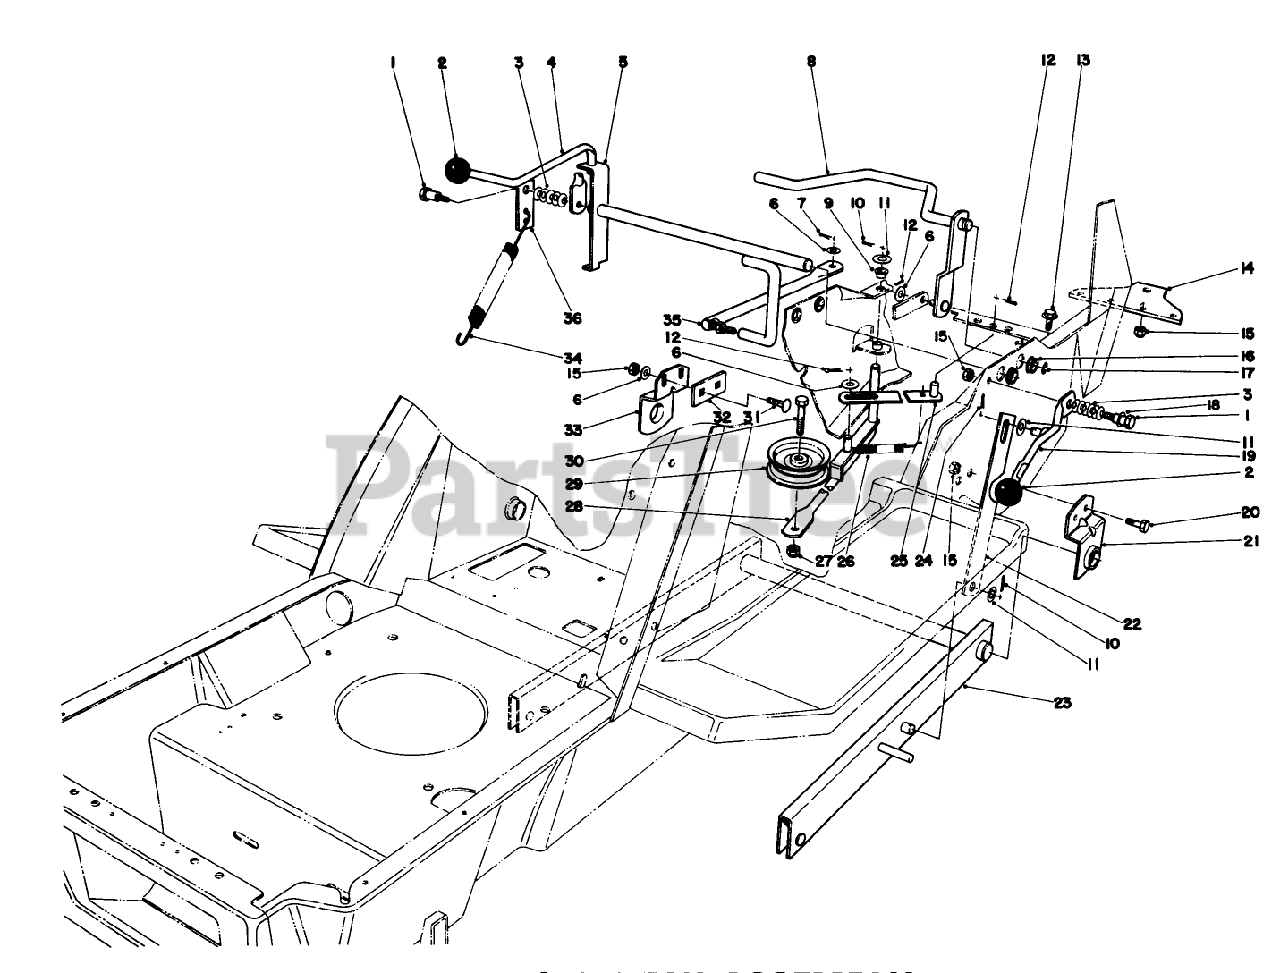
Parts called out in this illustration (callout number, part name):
1	BOLT-SHOULDER
2	Knob
3	Belleville Washer
6	WASHER-PLAIN
7	PIN-COTTER
9	BUSHING-NYLINER
10	PIN-COTTER
11	WASHER-FLAT
12	PIN-COTTER
13	SCREW-HHF
15	NUT-LOCK, NI
17	E-RING
18	Washer
20	SCREW-HH
21	Retainer-Pivot Bar L.H.
24	PIN-COTTER
27	NUT-LOCK, CONE
28	IDLER ARM WA *BO
30	SCREW-HH
31	BOLT-CARR
33	Retainer-Pivot Bar R.H.
34	TRACTION SPRING
35	SHIFT ARM *BO
